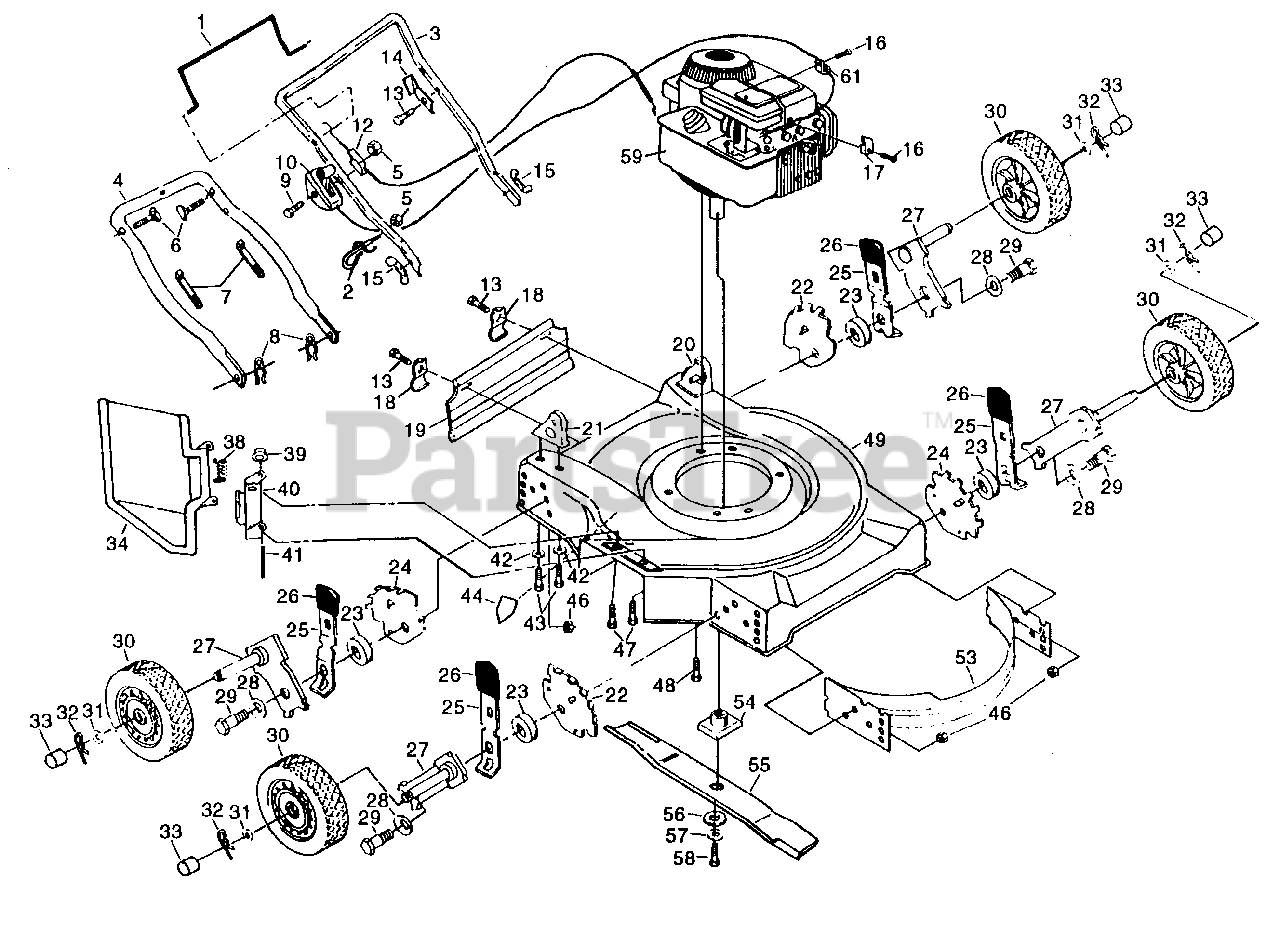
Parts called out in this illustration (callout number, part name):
1	Control Bar (AYP part number)
2	Rope Guide
3	Upper Handle (AYP part number)
4	Lower Handle (AYP part number)
5	Locknut (AYP part number)
6	Handle Bolt 5/16-18 x 1-3/4 (AYP part number)
7	Wire Tie (AYP part number)
8	Hairpin Cotter (AYP part number)
9	Hex Washer Head Screw 1/4-20 x 2.12 (AYP part number)
10	Throttle Control
12	Engine Zone Control Cable
13	Hex Washer Head Screw #10-24 x 1/2 (AYP part number)
14	Up-Stop Bracket (AYP part number)
15	Wing Nut (AYP part number)
16	Screw #10 x 5/8 (AYP part number)
17	Cable Clamp (AYP part number)
18	Skirt Bracket (AYP part number)
19	Rear Deflector (AYP part number)
20	Handle Bracket Assembly (Left) (AYP part number)
21	Handle Bracket Assembly (Right) (AYP part number)
22	Wheel Adjusting Bracket LR/RF
23	Height Adjuster Spacer (AYP part number)
24	Wheel Adjusting Bracket RR/LF
25	Selector Spring (AYP part number)
26	Selector Knob (AYP part number)
27	Axle Arm (AYP part number)
28	Belleville Washer (AYP part number)
29	Shoulder Bolt 3/8-16 x 1 (AYP part number)
30	Wheel Assembly (AYP part number)
31	Washer 17/32 x 1 x 21 Ga. (AYP part number)
32	Retainer Clip (AYP part number)
33	Hubcap (AYP part number)
34	Discharge Guard
38	Torsion Spring (AYP part number)
39	Push On Speed Nut (AYP part number)
40	Deflector Hinge (AYP part number)
41	Hinge Rod (AYP part number)
42	Flat Washer (AYP part number)
43	Screw 5/16-18 x 3/4 (AYP part number)
44	Danger Decal (AYP part number)
46	Locknut 3/8-16 (AYP part number)
47	Hex Head Thd. Rolling Screw 1/4-20 x 3/4 w/ Sems (AYP part number)
48	Hex Head Thread Rolling Screw 3/8-16 x 1 (AYP part number)
49	Mower Housing (Incl. Ref. #44)
53	Front Baffle (AYP part number)
54	Blade Adapter (AYP part number)
55	Blade 20"
56	Hardened Washer (AYP part number)
57	Helical Lockwasher 3/8 (AYP part number)
58	Hex Head Screw 3/8-24 x 1-3/8 (Grd. 8)
61	Guide Clip (AYP part number)
